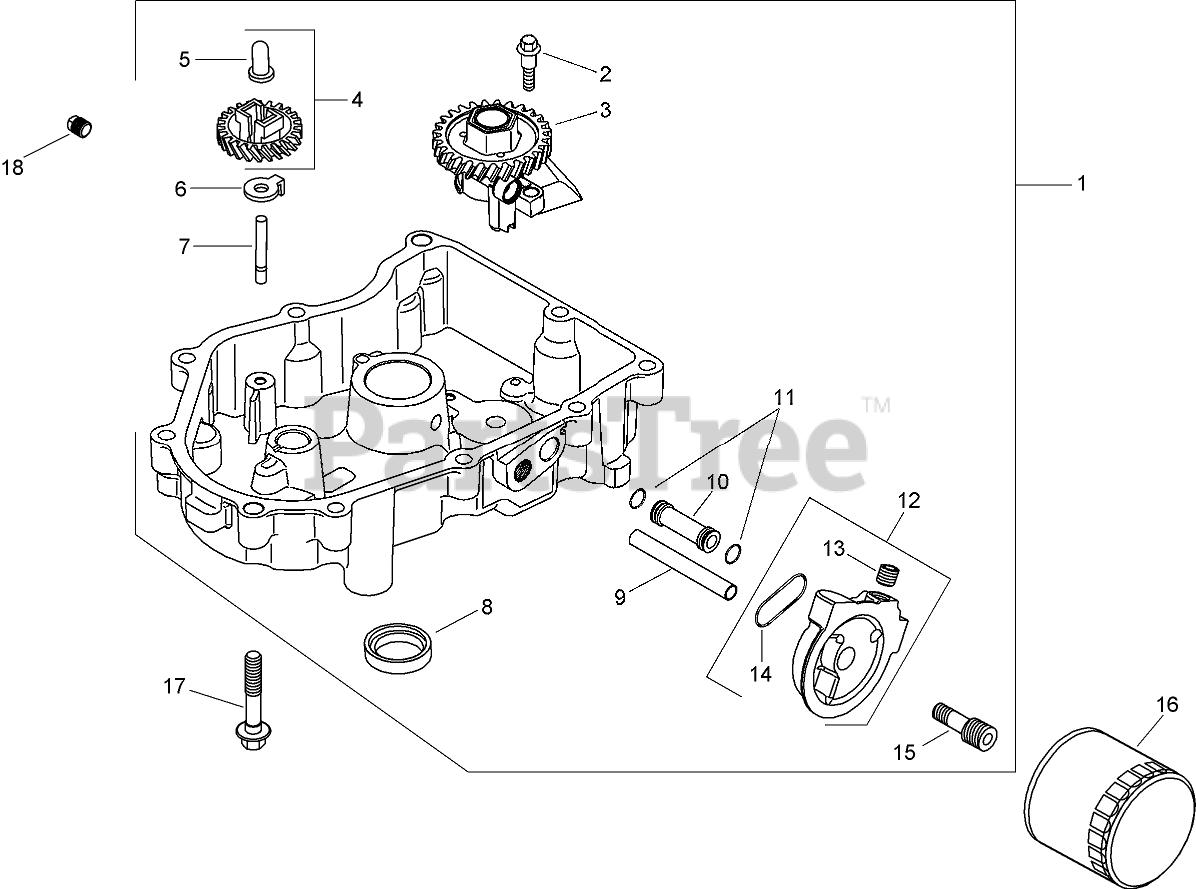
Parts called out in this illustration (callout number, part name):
1	OIL PAN ASM (INCLUDES 2-15)
2	SCREW-SHOULDER, THD FRM (M6x1.0x26.5)
3	OIL PUMP ASM
4	GOVERNOR GEAR KIT W/PIN (INCLUDES 5)
5	PIN-REGULATING, GOVERNOR
6	TAB-LOCKING
7	SHAFT-GEAR, GOVERNOR
8	SEAL-OIL (P-T-O END)
9	TUBE-FEED, OIL (FILTER TO PAN)
10	TUBE-FEED, OIL (PAN TO FILTER)
11	O-RING, OIL PICK-UP
12	Adapter-Filter, Oil (INCLUDES 13, 14)
13	PLUG-PIPE, COUNTERSUNK (1/8)
14	O-RING
15	NIPPLE-FILTER, OIL
16	FILTER-OIL
17	SCREW-FLANGE (M8X1.25X45)
18	PLUG-PIPE, SQ HD (3/8)
